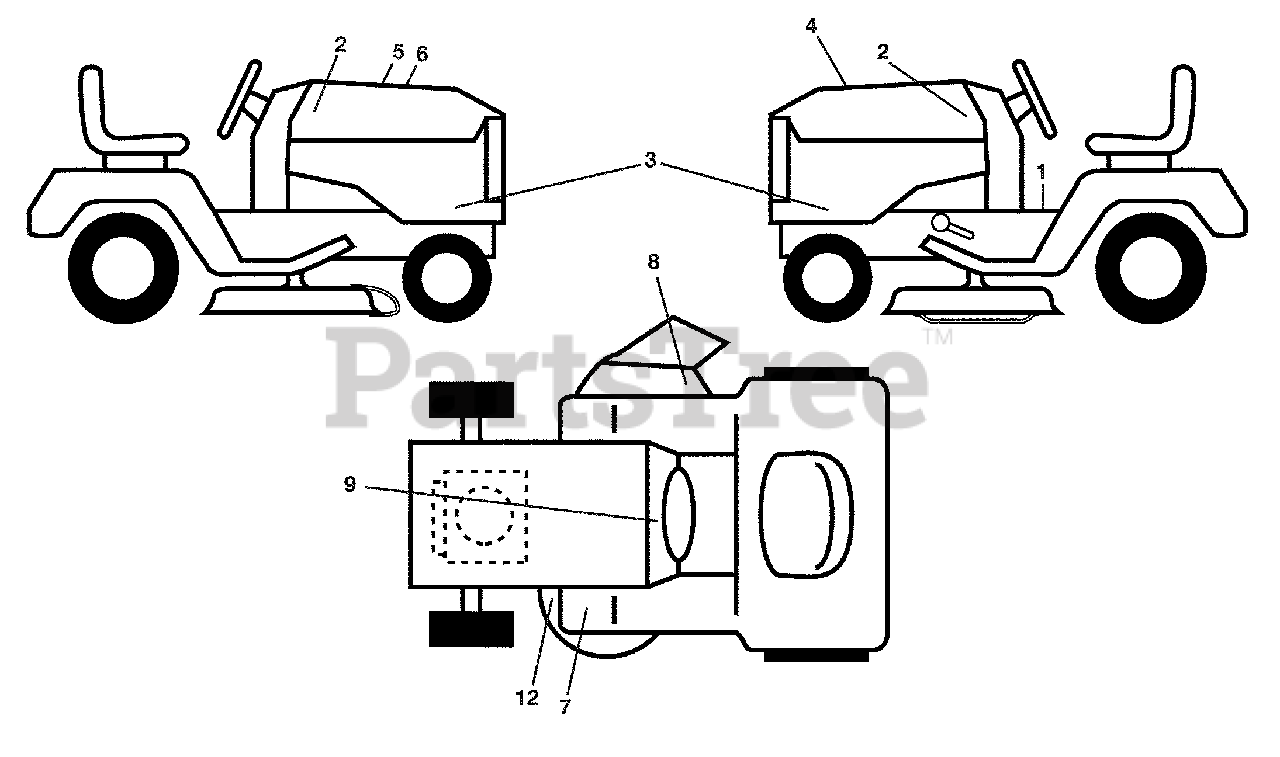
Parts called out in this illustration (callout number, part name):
1	Decal, Operators
2	Decal, Hood
3	Decal, Emblem Panel SD
4	Decal, Engine
5	Decal, Customer Respons.
6	Decal, Replacement
7	Decal, Pedal Husq. Crown
8	Decal, Warning Keep Hand Away
9	Decal, Battery Dnge/Poi
12	Decal, Mower V-Belt Schematic
